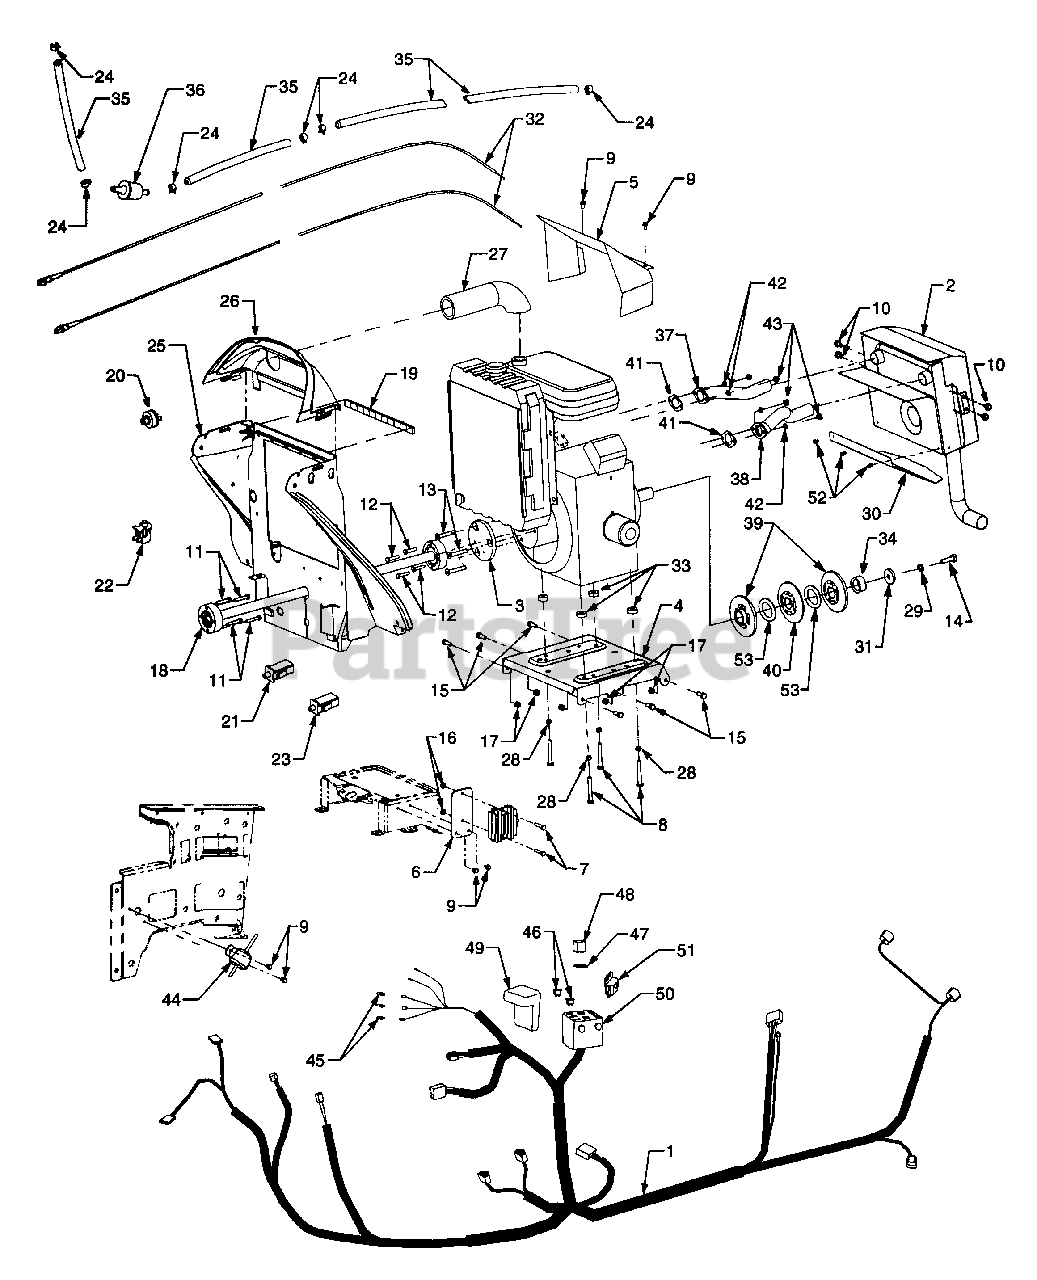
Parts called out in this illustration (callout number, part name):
1	Harness, Wire
2	Muffler Assembly
3	Plate, Coupling Adapter
4	Plate, Engine Mounting
5	Shield, Muffler Heat
6	Plate, Regulator Mounting
7	Screw, Hex Cap, 1/4-20 x 1.25 GR5
8	Screw, Hex Cap, 5/16-18 x 2.5 GR5
9	Screw, Hex Wash. Hd. Tapp 1/4-20 x .5
10	Screw, Hex Wash. Hd. Tapp 5/16-18 x .5
11	Screw, Hex Wash. Hd. Tapp 1/4-20 x 1.5
12	Screw, Hex Cap, Lock 1/4-20 x 1.25 GR5
13	Screw, Countersink Machine, M8 - 1.25 x 55MM
14	Screw, Hex Cap, M10-1.5 x 35MM
15	Screw, Hex Cap, 5/16-18 x .875 GR5
16	Nut, Hex Sems, 1/4-20
17	Nut, Hex Insert Lock, 5/16-18
18	Shaft, Drive, 27.75 Long
19	Foam Tape 46 in.
20	Switch, Key
21	Switch, Plunger
22	Switch, Snap Mount
23	Switch, Plunger
24	Clamp, Hose
25	Baffle, Lower Air
26	Baffle, Upper Air
27	Hose, Intake
28	Washer, Lock, 5/16
29	Washer, Lock, 7/16
30	Shield, Lower Exhaust
31	Washer, Flat, .417 x 1.5 x .225
32	Cable, Choke and Throttle Control
33	Spacer, Engine, 1.0 O.D, x .34 Lg
34	Spacer, Crankshaft
35	Fuel Line, 12 inches
35	Fuel Line
36	Filter, Fuel
37	Pipe, Exhaust
38	Pipe, Exhaust
39	Pulley Half
40	Pulley, Center
41	Gasket, Exhaust
42	Washer, Lock, 6MM
43	Nut, Hex, 6MM
45	Bulb, Indicator
46	Fuse, 25 Amp
47	Gasket, Silicone
48	Relay, PTO
49	Cover, Fuse Box
50	Box, Fuse
51	Sensor, Voltage
52	Screw, Hex Wash. Hd. Tapp. #12-24 x .375
53	Washer, Flat Shim (Hdn)
